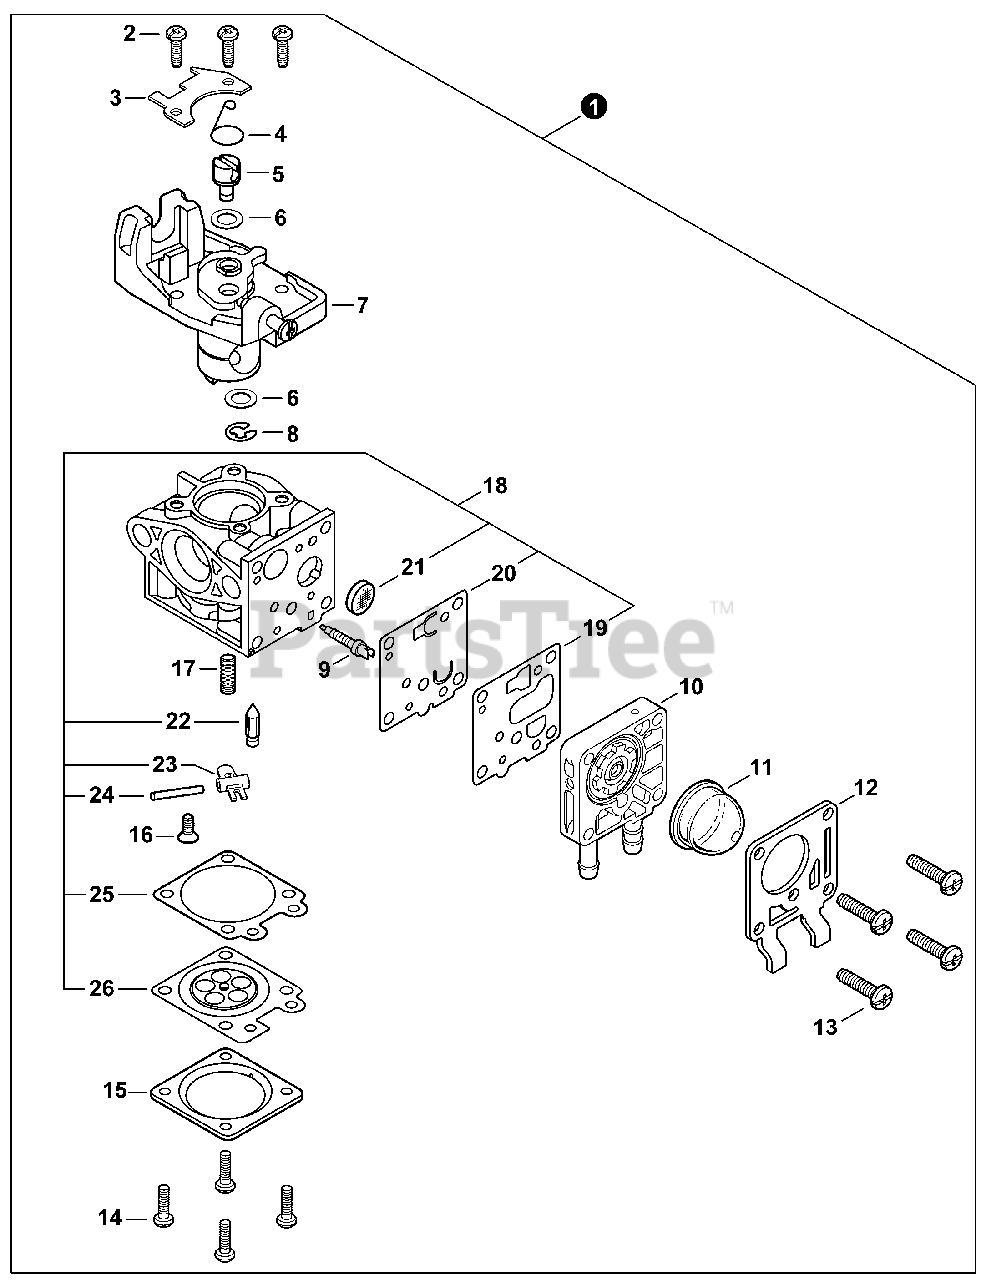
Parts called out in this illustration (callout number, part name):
1	CARBURETOR - WYG-11
7	THROTTLE VALVE ASSY
9	NEEDLE, MIXTURE
10	BODY ASSY, PUMP
11	BULB, PURGE
12	COVER, FUEL PUMP
15	COVER, METERING DIAPHRAGM
18	REPAIR KIT, CARBURETOR
19	GASKET, FUEL PUMP
20	DIAPHRAGM, FUEL PUMP
21	SCREEN, FUEL INLET
22	VALVE, INLET NEEDLE
23	LEVER, METERING
24	PIN, METERING LEVER
25	GASKET, METERING DIAPHRAGM
26	DIAPHRAGM, METERING
